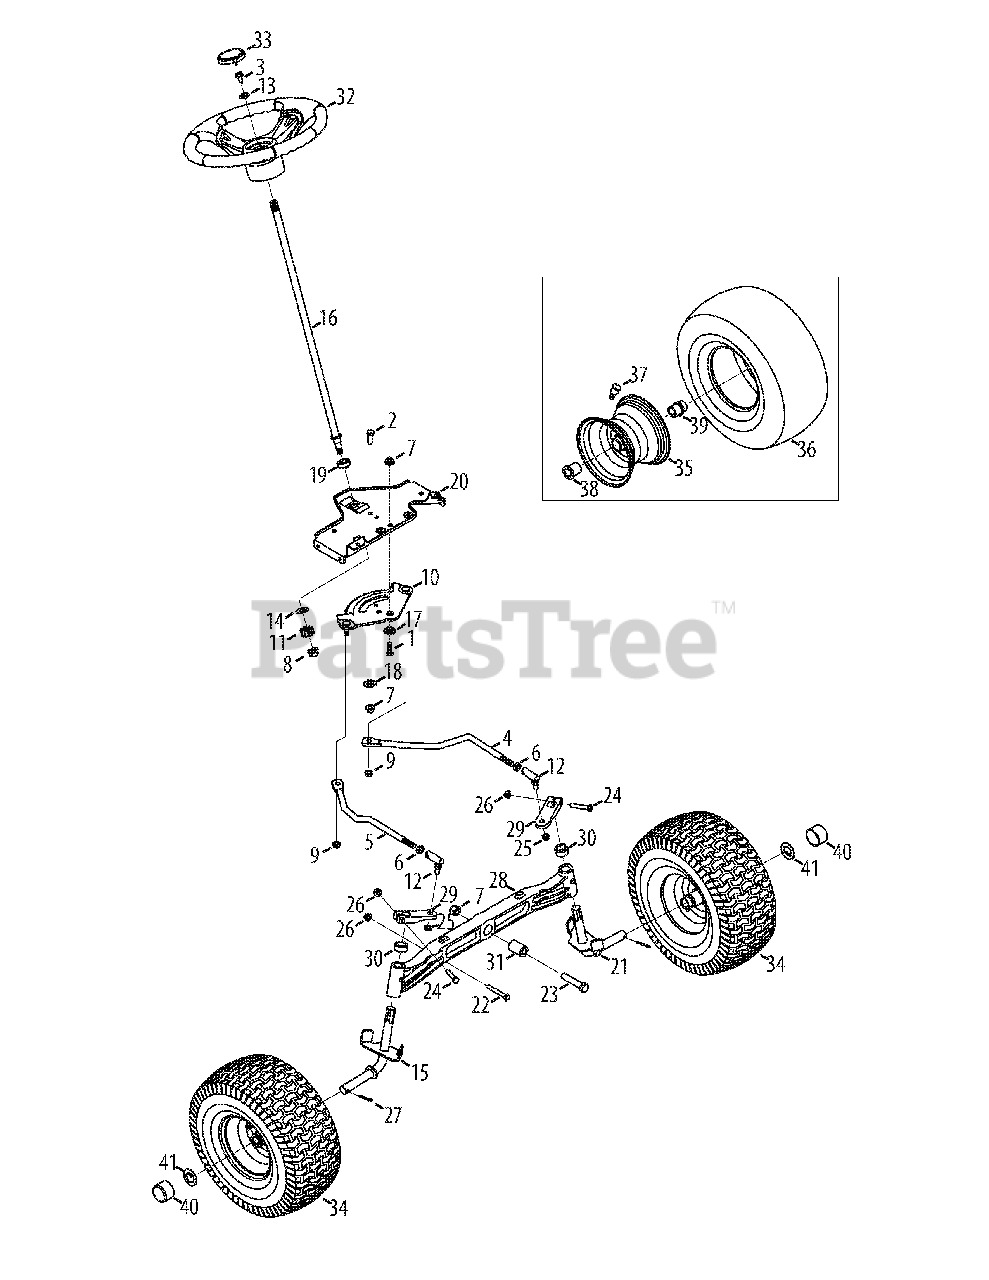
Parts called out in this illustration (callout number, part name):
1	Hex Head Screw, 3/8-16:1.00
2	Hex Head Screw, 3/8-16:1.00
3	Hex Head Screw, 5/16-18:1.00
4	LH Drag Link
5	RH Drag Link
6	Jam Nut, 7/16-20
7	Flangelock Nut, 3/8-16
8	Flangelock Nut, 7/16-20
9	Flangelock Nut, 5/16-18
10	Steering Gear
11	Steering Pinion Gear
12	Ball Joint, 7/16-20
13	Flat Washer, .406 x .875 x .105
14	Flat Washer, .51 x 1.12 x .06
15	RH Axle Assembly
16	Steering Shaft, .625 OD x 24.25 LG
17	Shoulder Spacer, .385 x 1.25 x .3025
18	Spacer, .38 x 1.375
19	Hex Flange Bearing 5/8 PM
20	Steering Support Bracket
20	Screw, .750 5/16-18
21	LH Axle Assembly
22	Hex Head Screw, 5/16-18:2.25
23	Hex Head Screw, 3/8-16:2.50
24	Hex Head Screw, 5/16-18:1.75
25	Hexlock Nut, 3/8-24
26	Flangelock Nut, 5/16-18
27	Cotter Pin, 5/32:1.25
28	Pivot Bar Axle
29	Steering Block
30	Spacer, .71 ID x .125 OD x .56LG
31	Spacer, .385 x 1.00 x 1.5075
32	Steering Wheel
33	Steering Wheel Cap
34	Wheel Assembly
35	Rim Assembly
37	Tubeless Air Valve
38	Flange Bearing, .760 x 1.00 x 1.20LG
39	Flange Bearing, .760ID
40	Bumper Cap
41	Flat Washer, .781ID x 1.590OD
